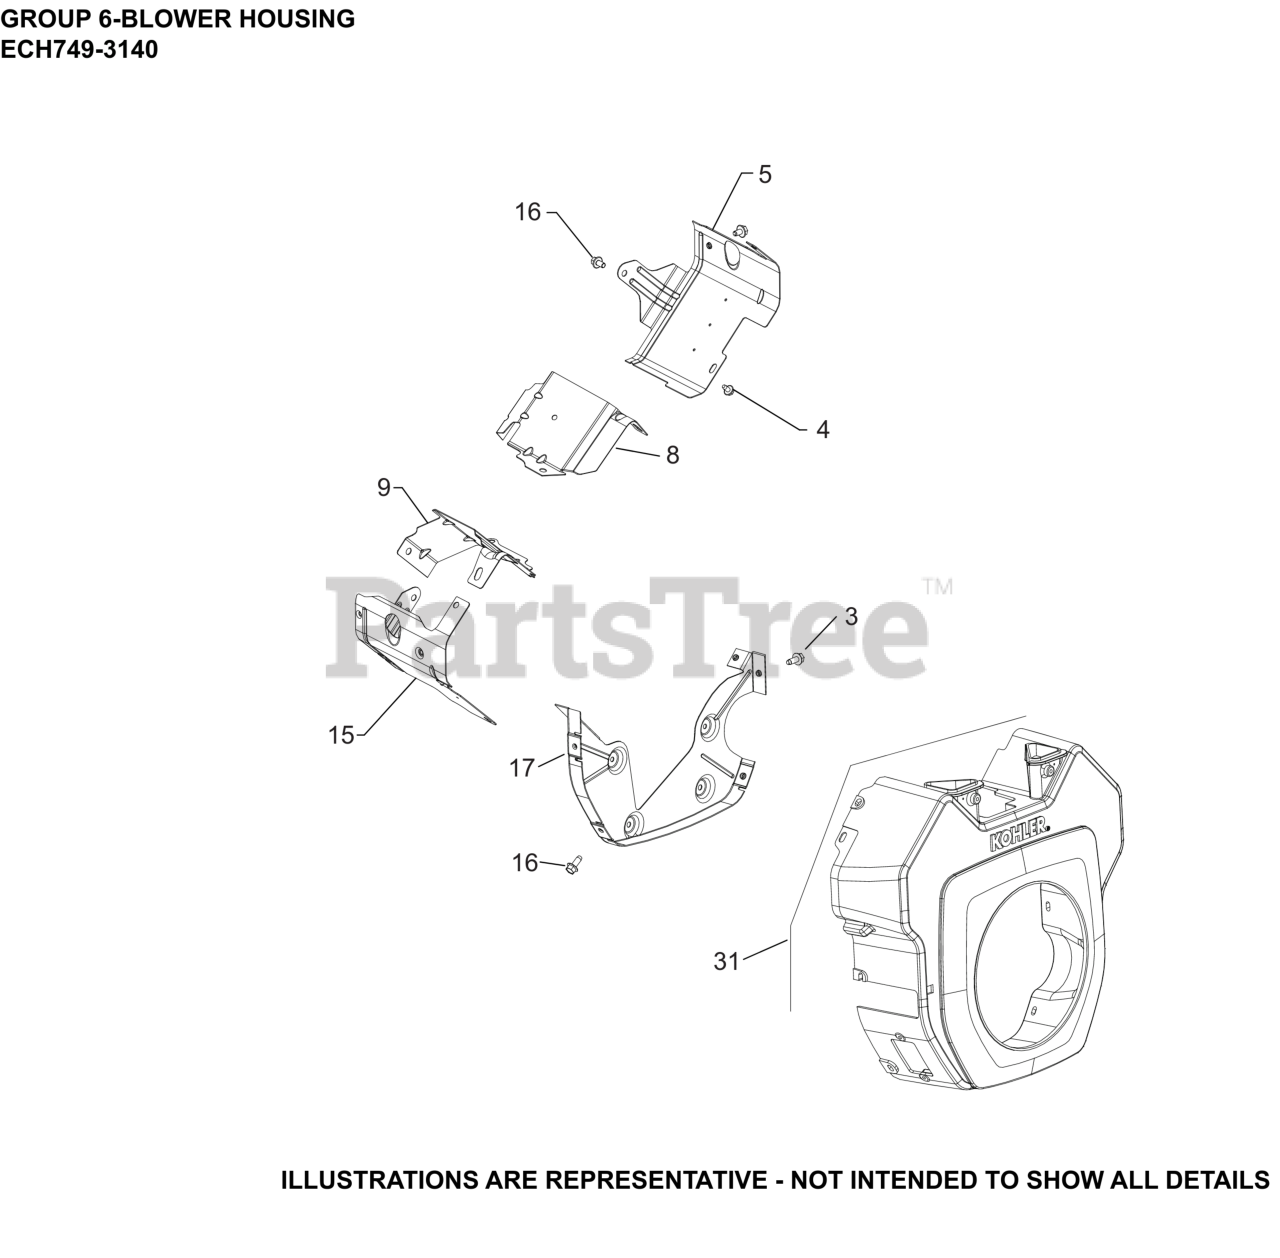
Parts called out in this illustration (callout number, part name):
3	SCREW, THREAD FORMING
4	SCREW, THREAD FORMING
5	BAFFLE, RIGHT BARREL
8	BAFFLE, VALLEY #1 CYLINDER
9	BAFFLE, VALLEY #2 CYLINDER
15	BAFFLE LEFT BARREL
16	SCREW, THREAD FORMING
17	KIT, BACKING PLATE
31	KIT, BLOWER HOUSING
NI	STRAP, LIFTING
